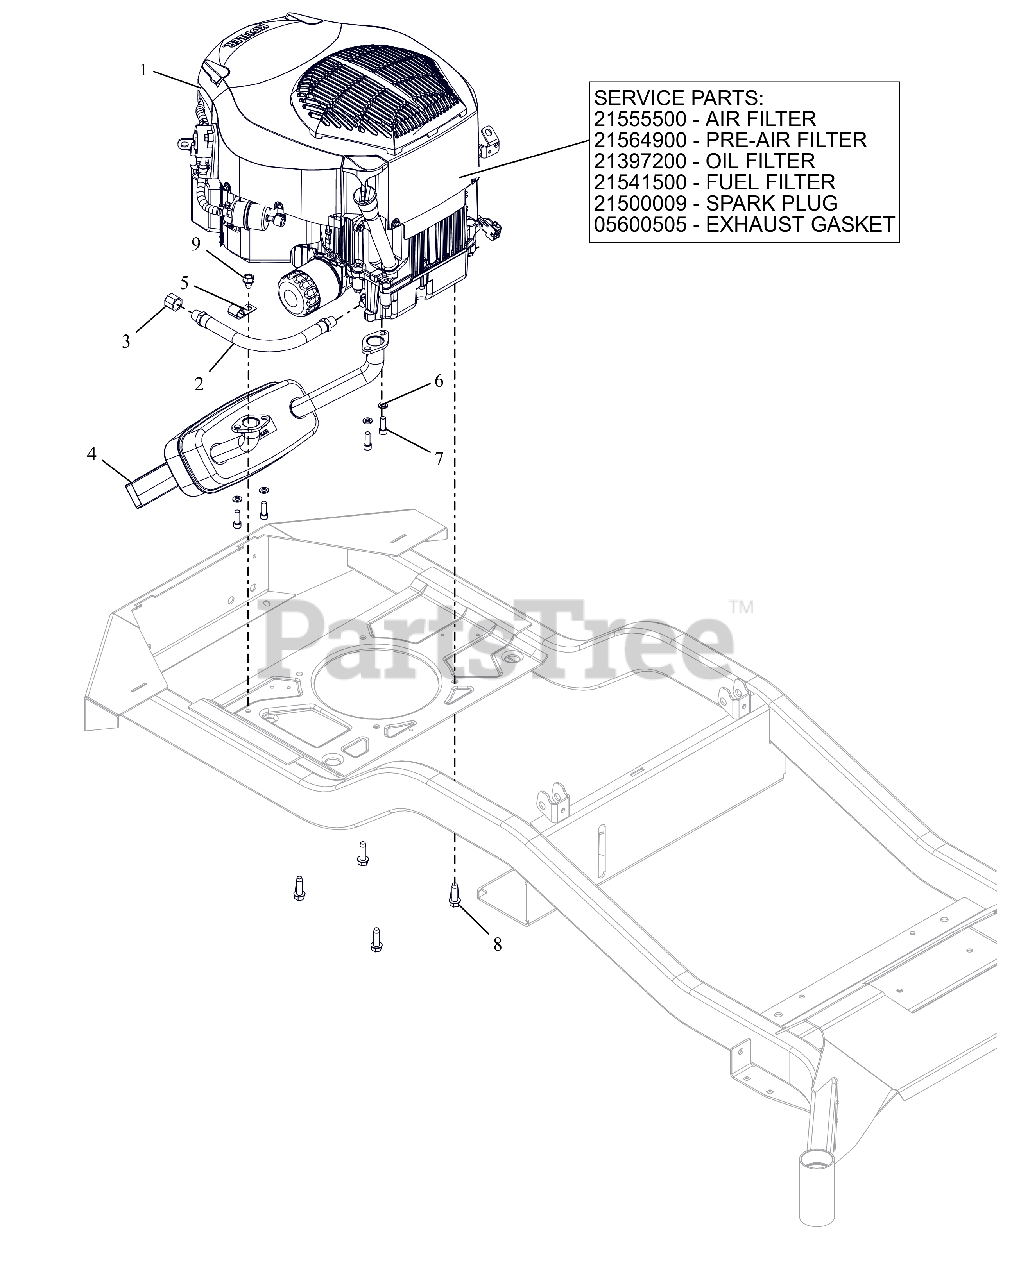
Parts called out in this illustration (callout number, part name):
1	ENGINE, KOHLER - KT730
1	AIR CLEANER, KOHLER
1	PRE-CLEANER, KOHLER
1	FILTER, OIL - KOH CV20
1	FILTER, FUEL
1	PLUG, SPARK KOHLER
1	GASKET, MUFFLER COURAGE TWIN
2	HOSE,HYD .38-11-0K M6NO-M6N0
3	PIPE CAP 3/8 NPT FEMALE
4	MUFFLER, KOHLER
5	J-CLAMP
6	@WSHR-LK .31X.078 REG YWZC
7	SCR-CAP .31-18X.88 S/HD G8 ZCC
8	@SCR-TAP .38-16X1.25 HWH TR YZ
9	@SCR-TAP .38-16X.50 HWH TR YWZ
